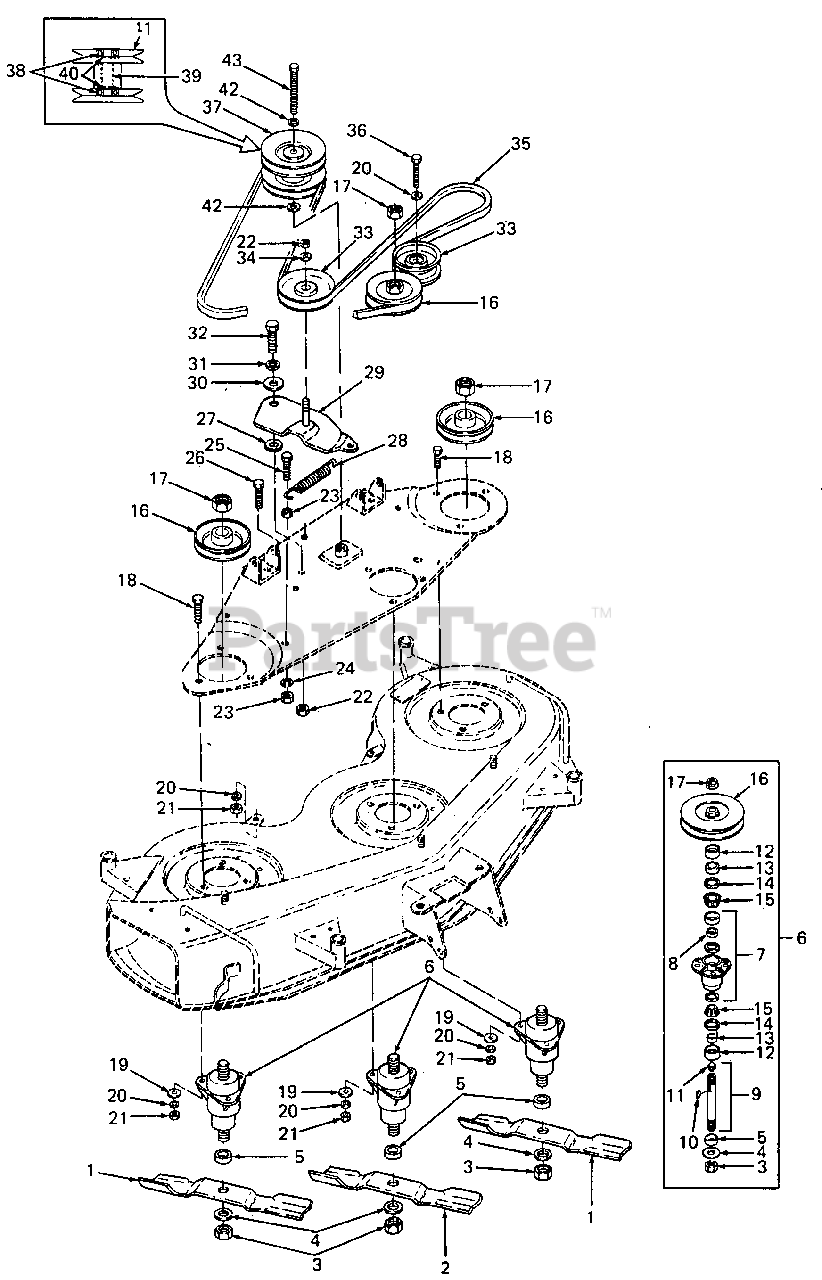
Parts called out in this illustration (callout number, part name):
1	Blade, Low Lift, 16.28 Lg
2	Blade, Low Lift, 14.88 Lg
3	Nut, Hex, 3/4-16 GR8
4	Washer, Flat, .781 X 2.0 X .105 Thk
5	Spacer, Blade
6	Spindle Service Kit
7	Housing, Spindle w/Cups
8	Spacer, Bearing
9	Kit, Shaft w/Seal
10	Key, #91 Woodruff, 1/4 X 3/4 HDN
11	Fitting, Lube, 3/16
12	Cup, Spindle HDN
13	Spacer, .755 X 1.25 X .44 Lg
14	Seal, Oil, 1.25 X 1.874 X .25
15	Cone, Bearing
16	4L V-Pulley, 4.62 OD X .75 ID
17	Nut, Hex Jam, 3/4-16
18	Screw, Hex Cap, 3/8-16 X 1.25 GR5
19	Washer, Flat, .378 X 1.0 X .127 Thk
20	Washer, Lock, 3/8 Dia
21	Nut, Hex, 3/8-16
22	Nut, Hex Center Lock, 3/8-16 GR5
23	Nut, Hex, 1/4-28
24	Washer, Lock, 1/4 Dia
25	Screw, Hex Cap, 1/4-28 X 1.25 Lg GR5
26	Screw, Hex Cap, 3/8-16 X 1.0 Lg GR5
27	Washer, Flat, .385 X .88 X .06 Thk HDN
28	Spring, Extension, .88 OD X 4.00 Lg
31	Washer, Bell, 3/8 Dia
32	Screw, Hex Cap, 3/8-16 X 1.25 Lg GR5
33	Idler, Flat, 3.5 OD
34	Washer, Flat, .406 X .75 X .63 Thk
35	V-Belt, 1/2 X 105.0 Lg
36	Screw, Hex Cap, 3/8-16 X 2.0 Lg GR5
37	Pulley Assy, Double
38	Bearing, Ball, .62 ID X 1.38 OD X .44 Thk
39	Spacer, Pulley, .64 ID X .81 OD X 2.25 Lg
40	Snap Ring, Internal
42	Washer, Flat, .63 ID X 1.0 OD X .63 Thk HDN
43	Bolt, Hex, 5/8-18 X 4.25 Lg GR5
